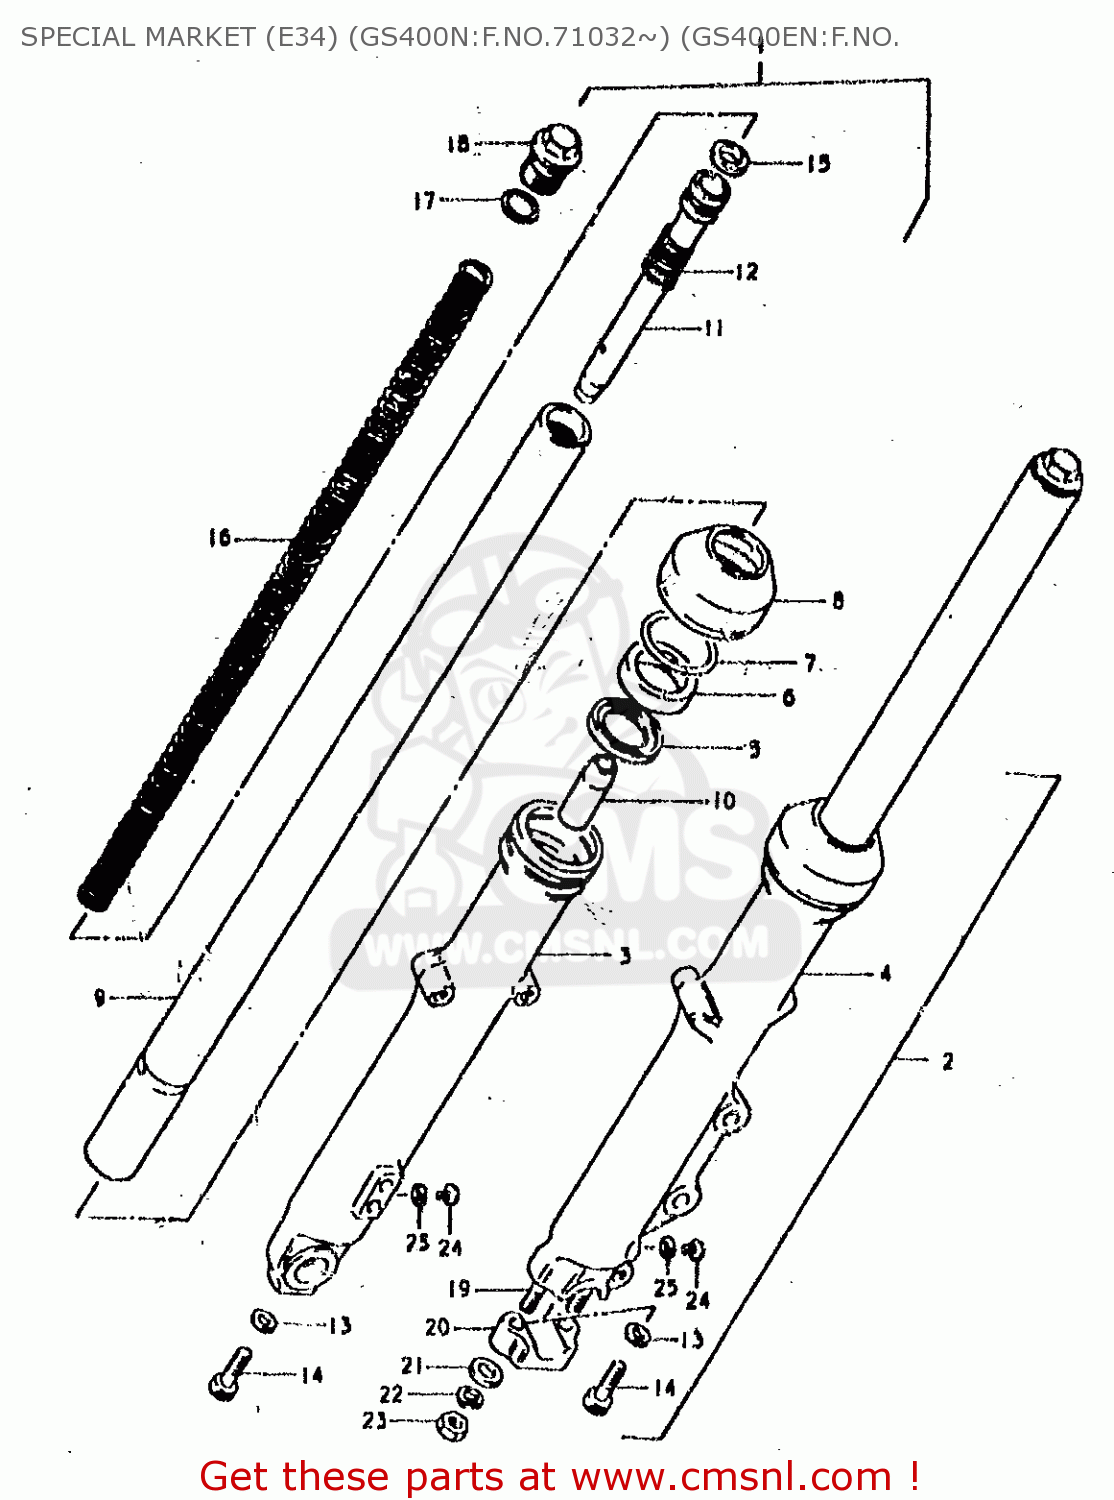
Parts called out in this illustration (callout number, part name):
1	DUMPER ASSY,RH
2	DUMPER ASSY, FRONT FORM LH
3	TUBE,FORK,OUTER,RIGHT
4	TUBE,FORK,LEFT,OUTER
5	SPACER,OIL SEAL
6	OIL SEAL,FRONT FORK
7	CIRCLIP,FORK OIL SEAL
8	BOOT
9	TUBE,INNER
10	PIECE,OIL LOCK
11	CYLINDER,FRONT FORK
12	SPRING,REBOUND
13	GASKET (NAS)
14	BOLT(8X27)
15	RING,PISTON
16	SPRING
17	O RING
18	BOLT
19	STUD 8X25
20	HOLDER,AXLE
21	WASHER
22	LOCK WASHER
23	NUT (8MM)
24	SCREW 4X6
25	GASKET (NAS)
